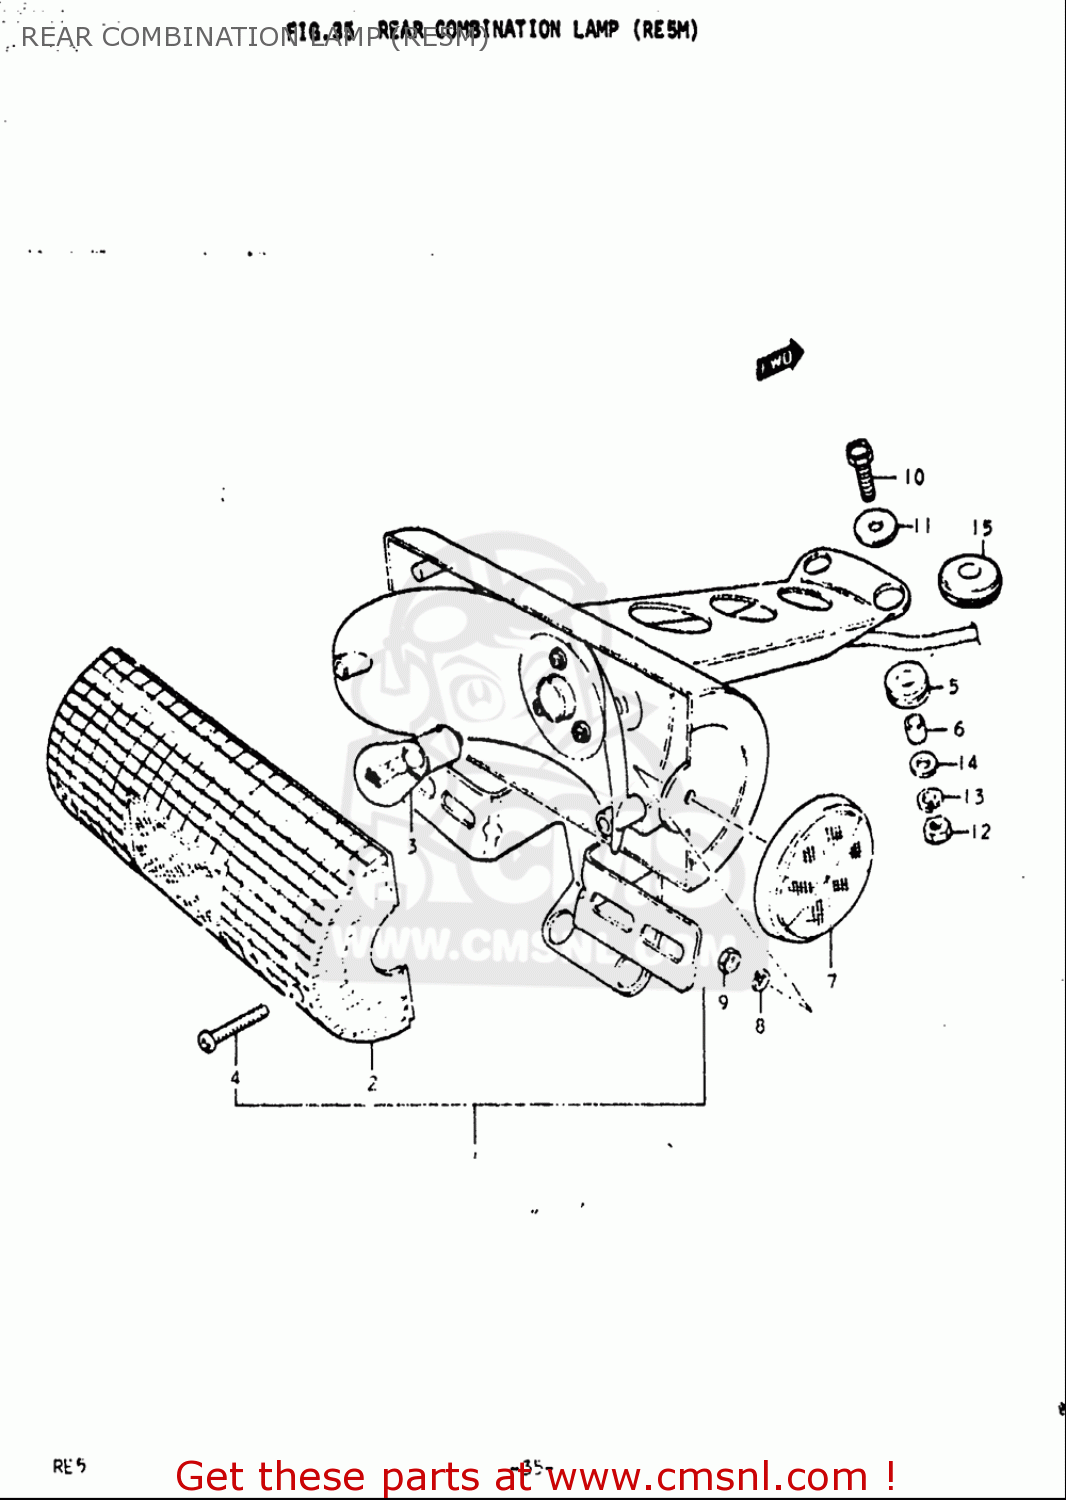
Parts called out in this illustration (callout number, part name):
3	BULB(12V23W)
5	CUSHION
6	SPACER
8	WASHER,LOCK
9	NUT
10	BOLT
11	WASHER(6.5X20X1.6)
12	NUT
13	WASHER,LOCK
14	WASHER
